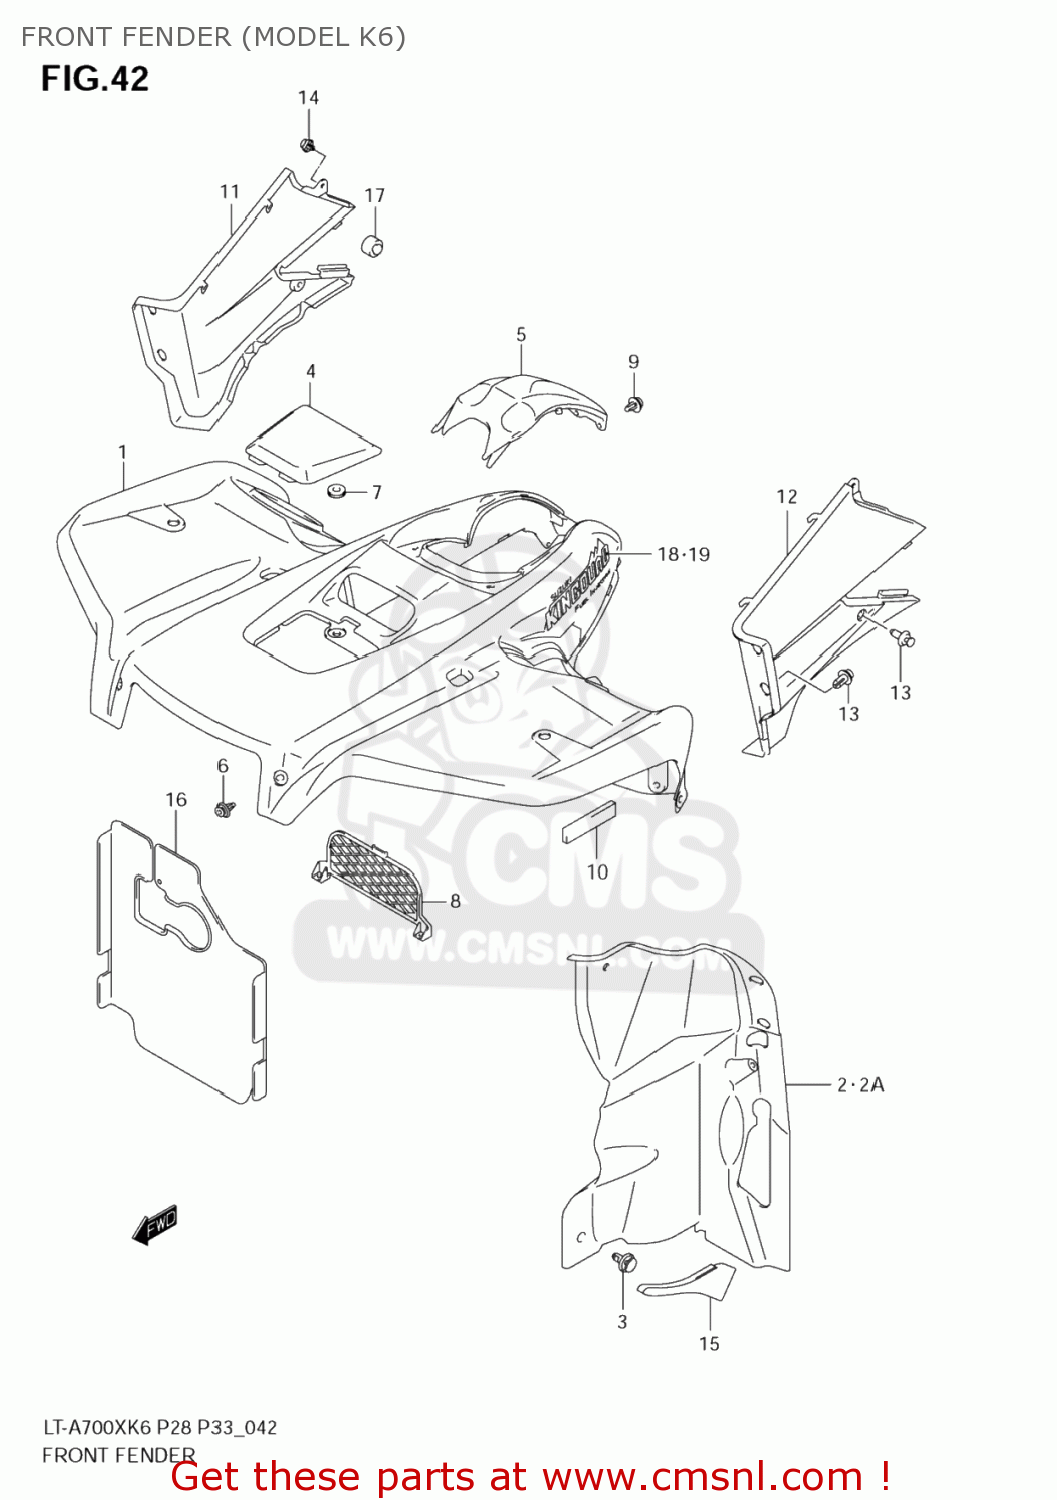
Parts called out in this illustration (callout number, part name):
1	FENDER,FR
2	MUD FLAP,FENDE
2A	MUD FRAP,FENDE
3	CLIP
4	LID,FENDER FR
5	FENDER,CENTER
6	CLIP
7	CUSHION
8	COVER,INNER
9	CLIP
10	CUSHION
11	COVER,SIDE,R(BLACK)
12	COVER,SIDE,L(BLACK)
13	CLIP
14	CLIP
15	MUDGUARD,SIDE,R
16	COVER,CTR
17	CUSHION
18	EMBLEM,FR FENDER,R
19	EMBLEM,FR FENDER,L
